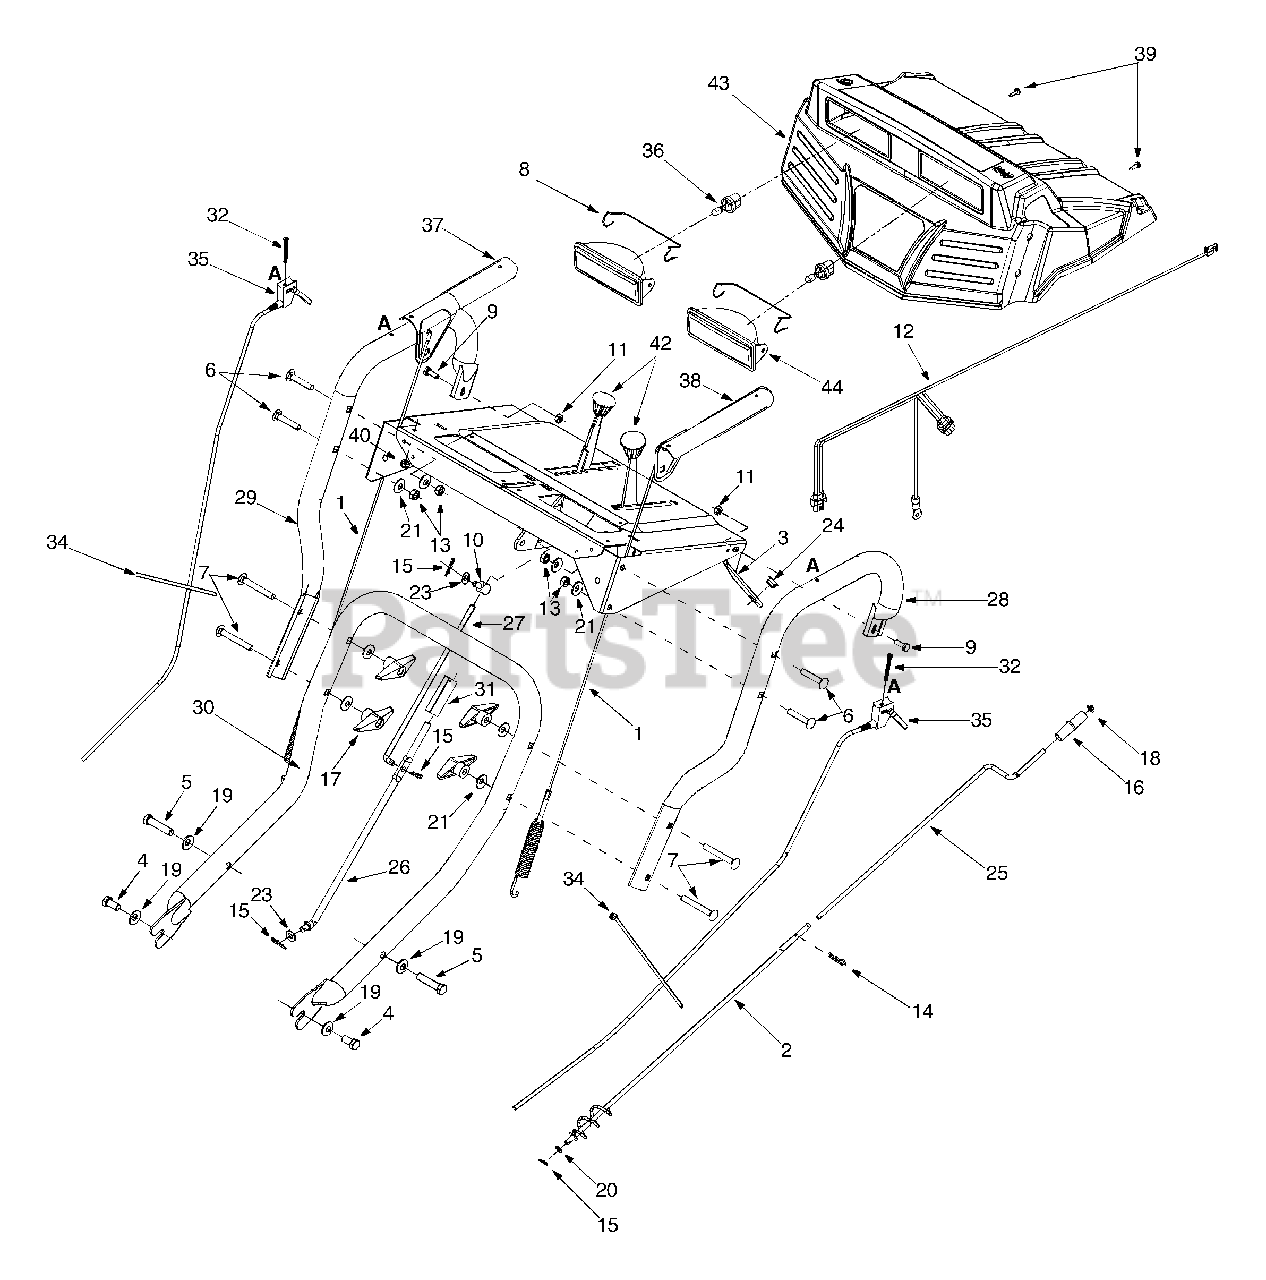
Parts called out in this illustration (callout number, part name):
1	Auger/Drive Cable Assembly
4	Hex Screw, 3/8-16 x.88"
5	Hex Screw, 3/8-16 x 1.75"
6	Carriage Bolt 5/16-18 x 1.75"
7	Carriage Bolt 5/16-18 x 2.5"
8	Lamp Retainer
9	Hex Screw 1/4-20 x 1.00"
10	Ferrule
11	Flange Lock Nut, 1/4-20
12	Lamp Wire Harness
14	Hairpin Clip
15	Hairpin Clip
16	Chute Directional Control Knob
19	Bell Washer
20	Flat Washer
21	Belleville Washer
23	Flat Washer
24	Plastic Bushing
26	Lower Shift Rod
27	Upper Shift Rod
31	Shift Rod Connector
32	Oval C-Sunk Screw
34	Cable Tie
35	Trigger Control
36	Halogen Lamp
37	Handle Engagement RH
38	Handle Engagement LH
39	Special B Screw
40	Hex Sems Nut
42	Shift Knob
43	Handle Panel
44	Lens Assembly
